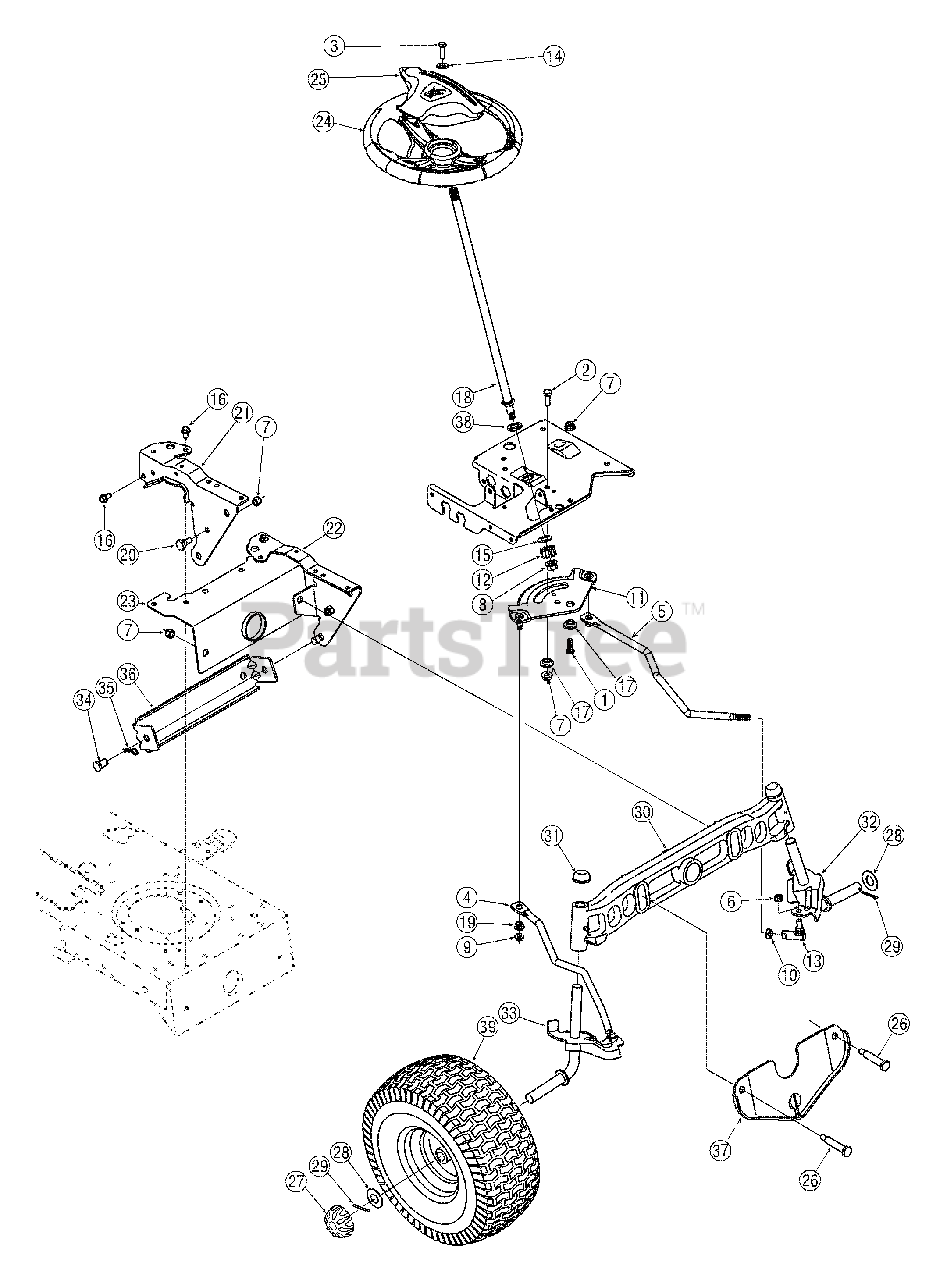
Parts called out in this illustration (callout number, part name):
1	Hex Screw, 3/8-16, 1.00, Gr5
2	Hex Screw, 3/8-16, 1.00, Gr5
3	Hex Screw, 5/16-18, 1.00, Gr5
4	Link, Drag, RH
5	Link, Drag, LH
6	Nut, Hex Lock, 3/8-24
7	Nut, Flange Lock, 3/8-16, Grf, Nylon
8	Nut, Flange Lock, 7/16-20
9	Nut, Flange Lock, 5/16-18, Gr5
10	Nut, Jam, 7/16-20, Gr2
11	Gear, Steering, 11/90 Ratio
12	Gear, Pinion, Steering
13	Ball Joint, 7/16-20, Lock
14	Washer, Flat,.406 x.875 x.105
15	Washer, Flat,.51 x 1.12 x.06
16	Screw, 5/16-12, 0.750
17	Spacer, Shoulder,.38 x 1.00 x.31
18	Shaft, Steering,.625 OD x 24.25 Lg
19	Plastic Bushing.380 ID
20	Screw, Shoulder,.498 x.340, 3/8-16
24	Steering Wheel, 3 Spoke, Soft Grip
25	Steering Wheel Cover (Model 604)
25	Steering Wheel Cap (Model 605)
26	Shlder Screw,.5 x 2.380, 3/8-16 (42" Deck)
26	Shlder Screw,.5 x 2.2, 3/8-16 (46" Deck)
27	Deluxe Hub Cap
28	Flat Washer,.78 x 1.589 x.06
29	Cotter Pin, 5/32 x 1.25
30	Cast Iron Pivot Bar
31	Push Cap
32	LH Axle Assembly,.750 (42" Deck)
32	LH Axle Assembly,.750 (46" Deck)
33	RH Axle Assembly,.750 (42" Deck)
33	RH Axle Assembly,.750 (46" Deck)
34	Pin, Clevis,.50 x.78 (46" Deck)
35	Cotter Pin, Inter,.080 x 1.5625 (46" Deck)
38	Hex Flange Bearing
